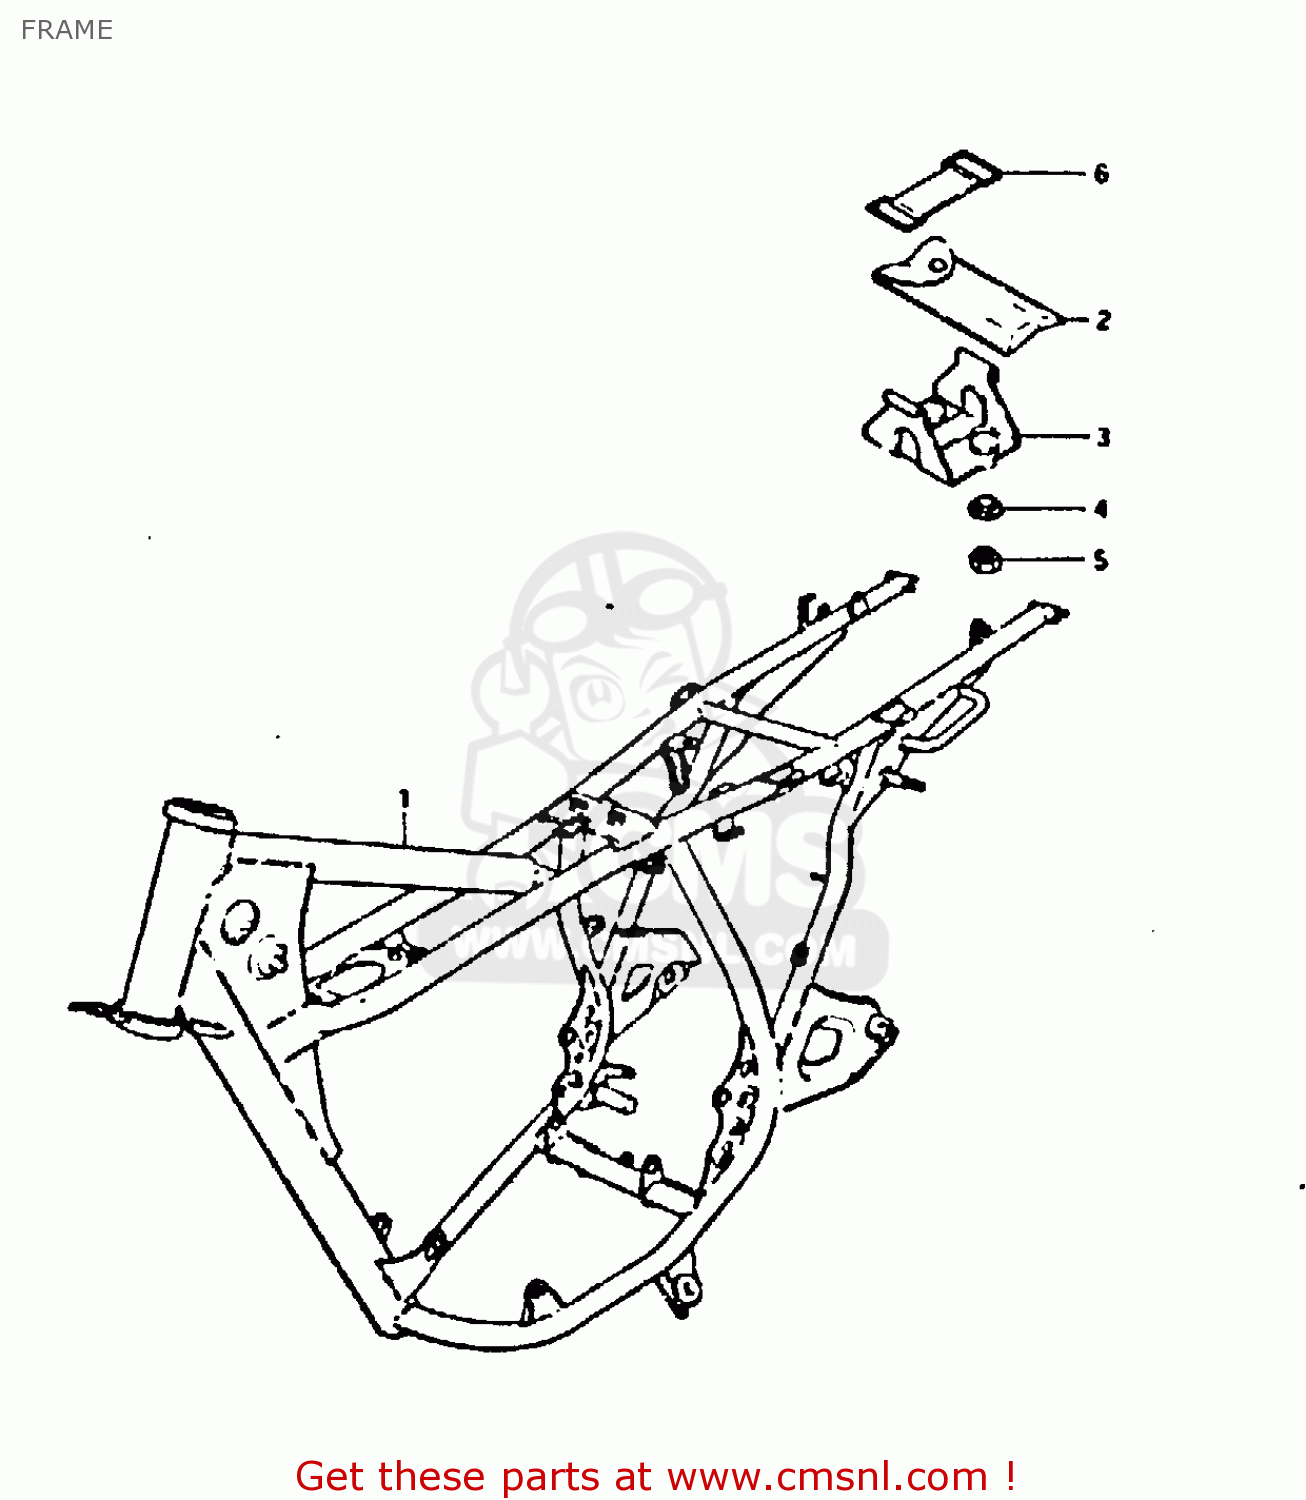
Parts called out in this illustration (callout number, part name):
1	FRAME (BLACK)
2	TOOL SET
3	HOLDER,TOOL
4	WASHER
5	NUT
6	BAND
